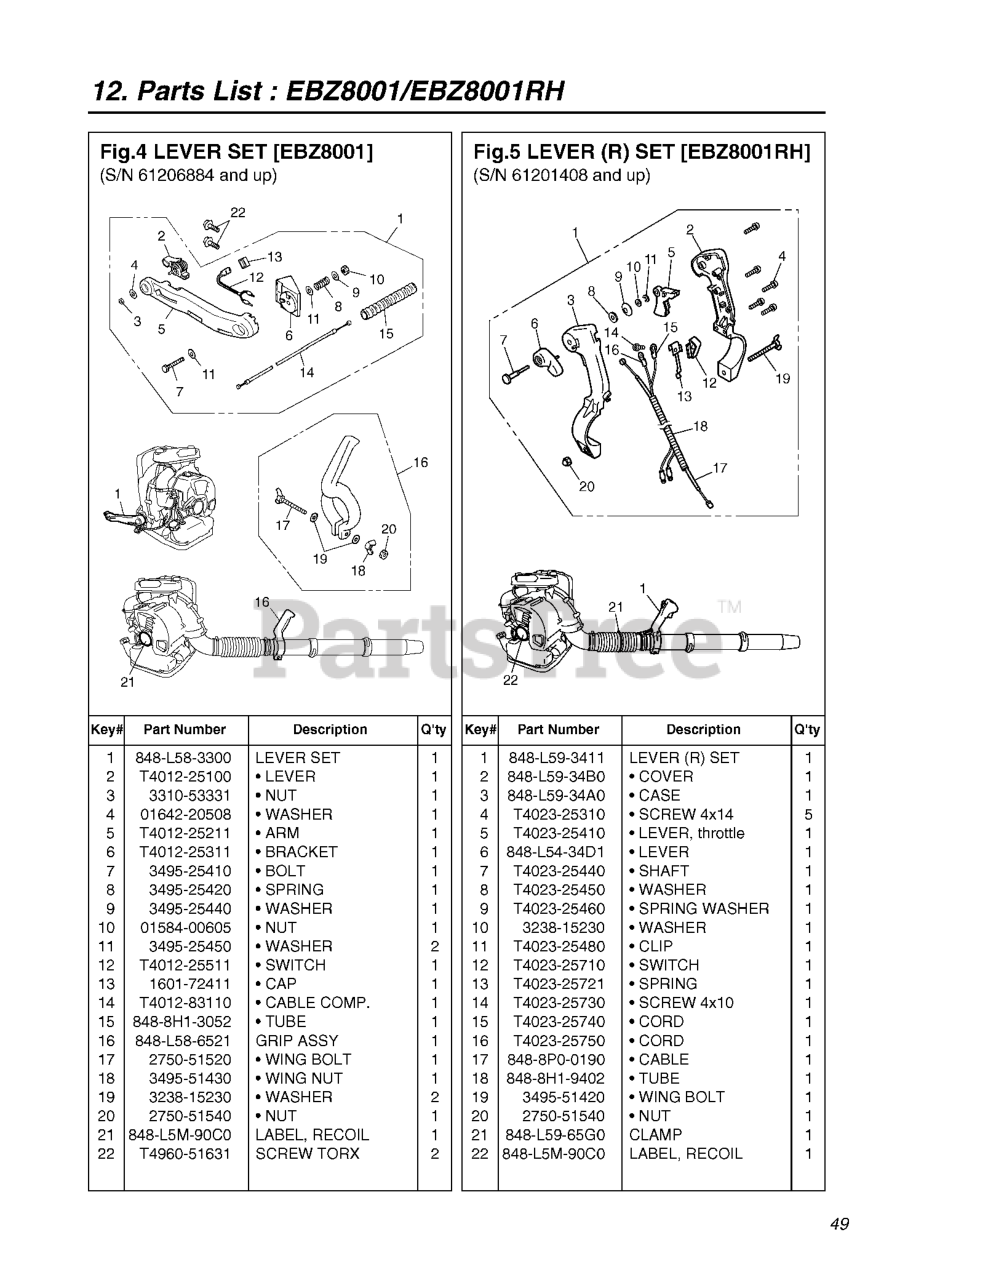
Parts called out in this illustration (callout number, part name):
4	WASHER
5	ARM
9	WASHER Z349525440
13	CAP SWITCH
14	RP_CABLE COMP
16	GRIP ASSY
17	WING BOLT
18	WING NUT
19	WASHER
